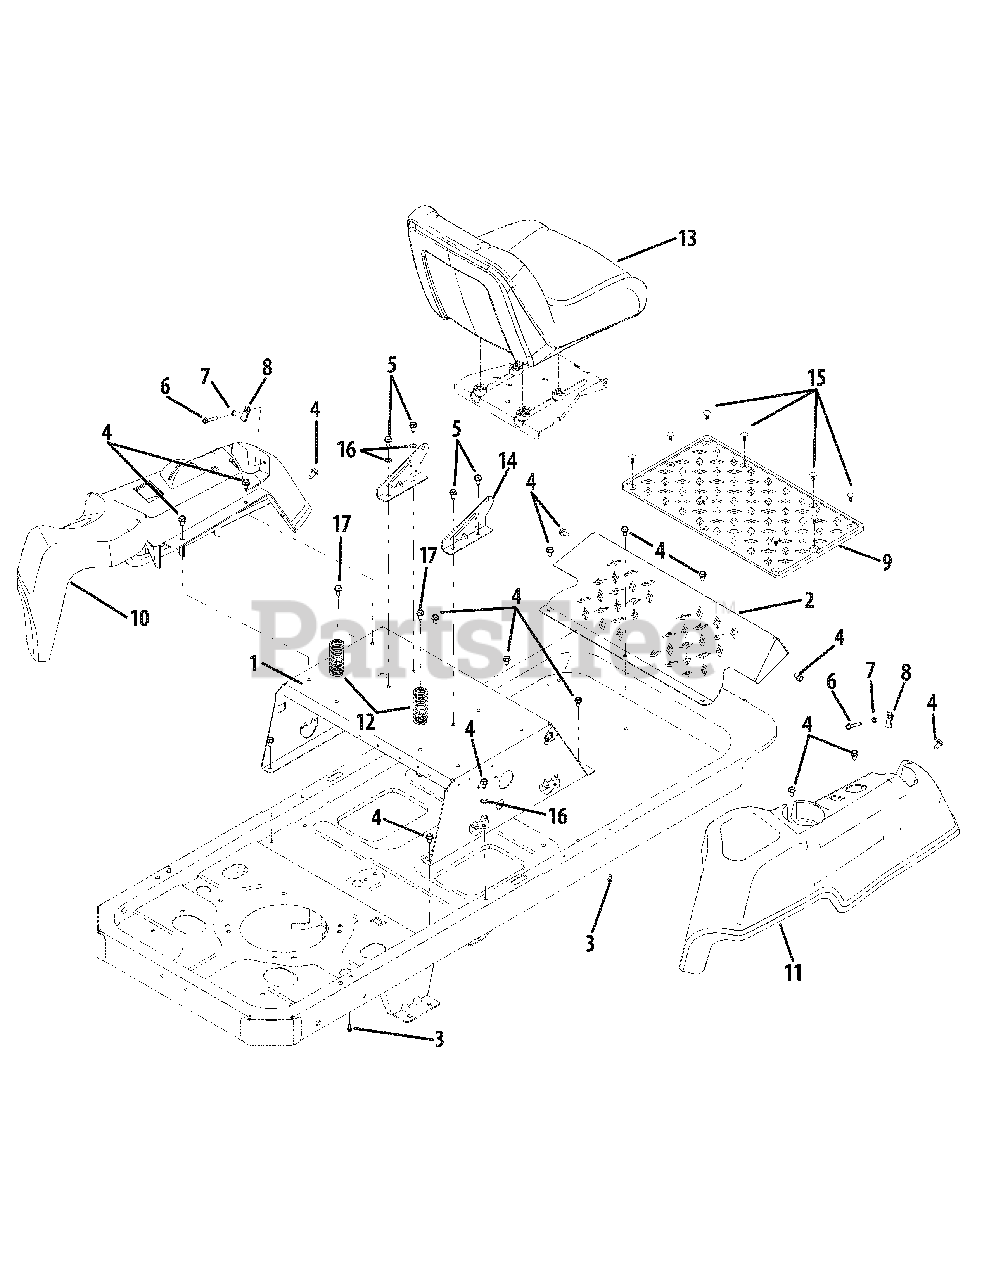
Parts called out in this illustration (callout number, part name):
4	Hex Screw, 5/16-18 x .625
5	Hex Screw, 5/16-12 x .75
6	Hex Screw, 1/4-20 x 1.5
7	Hex Nut, 1/4-20
8	U-Type Speed Nut, 1/4-20
9	Foot Pad
10	Left Hand Console
11	Right Hand Console
12	Compression Spring, 1.28 x 3.125
13	Seat
15	Ratchet Clip
16	External Tooth Washer, 3/8
17	Hex Screw, 5/16-18 x .75
